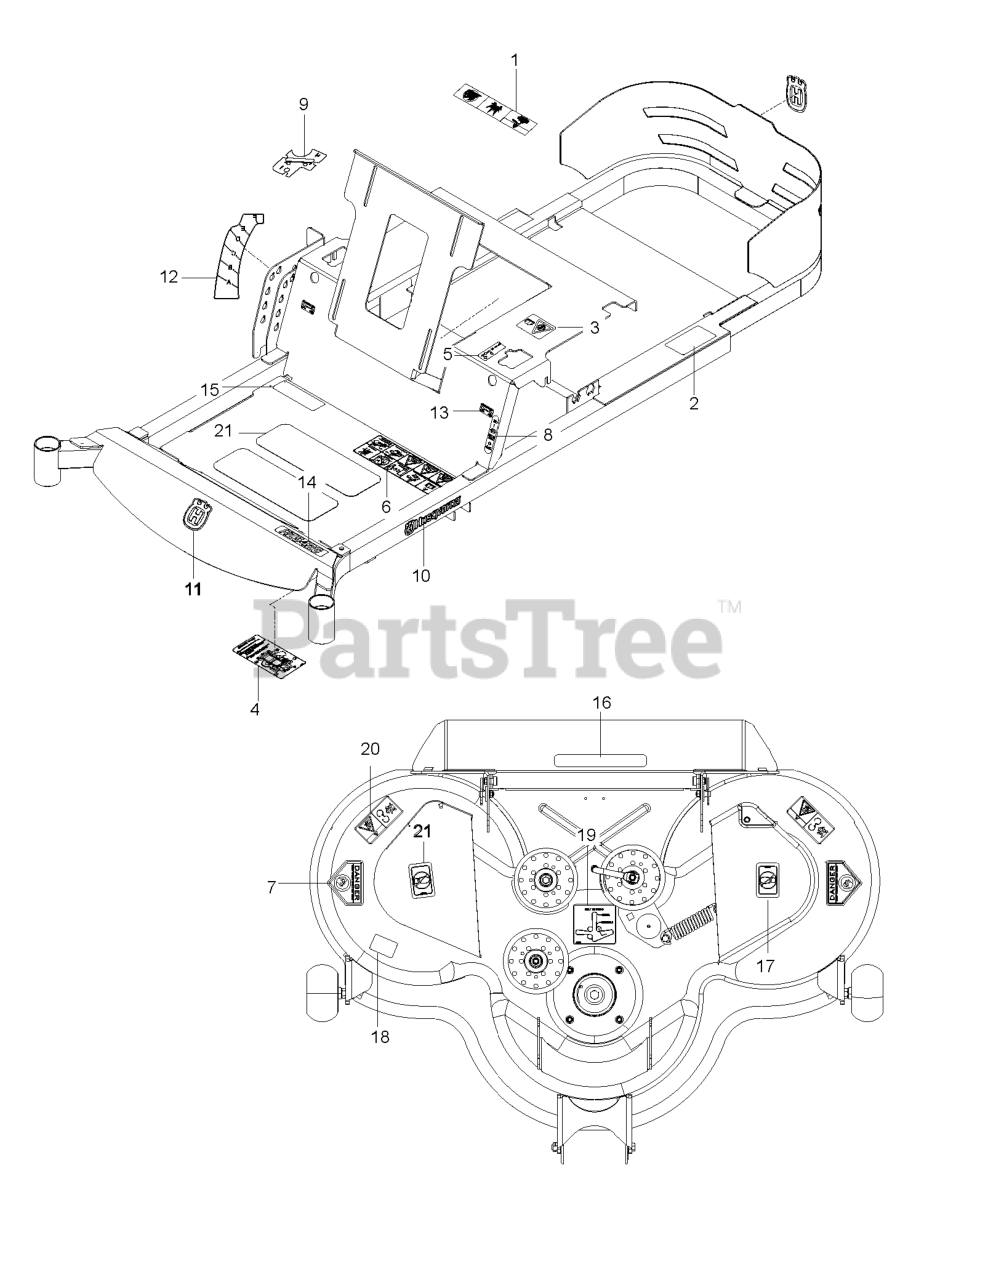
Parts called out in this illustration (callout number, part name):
1	EURO DECAL-BATTERY WARNIN6
2	DECAL, DO NOT TOW
3	DECAL, EXITING MOWER
4	DECAL, SERVICE
5	DECAL, MOTION CONTROL
6	DECAL, SAFETY WARNING
7	DECAL, CPSC
8	DECAL, PARK BRAKE
9	DECAL, CTRL PANEL, HUSQ
10	RP.DECAL.BADGE.170MM.TEXTLOGO
11	DECAL.AUGER.HUSQ.CROWN.SNOW
12	DECAL, DECK HEIGHT, HUSQ
13	DECAL, F.S.T.
14	DECAL, EZ24T
16	DECAL, DEFLECT WARNING
17	DECAL, NO STEP
18	DECAL, 122
19	DECAL, BELT ROUTING
20	DECAL, BELT DRIVE
21	ANTI-SKID PAD
